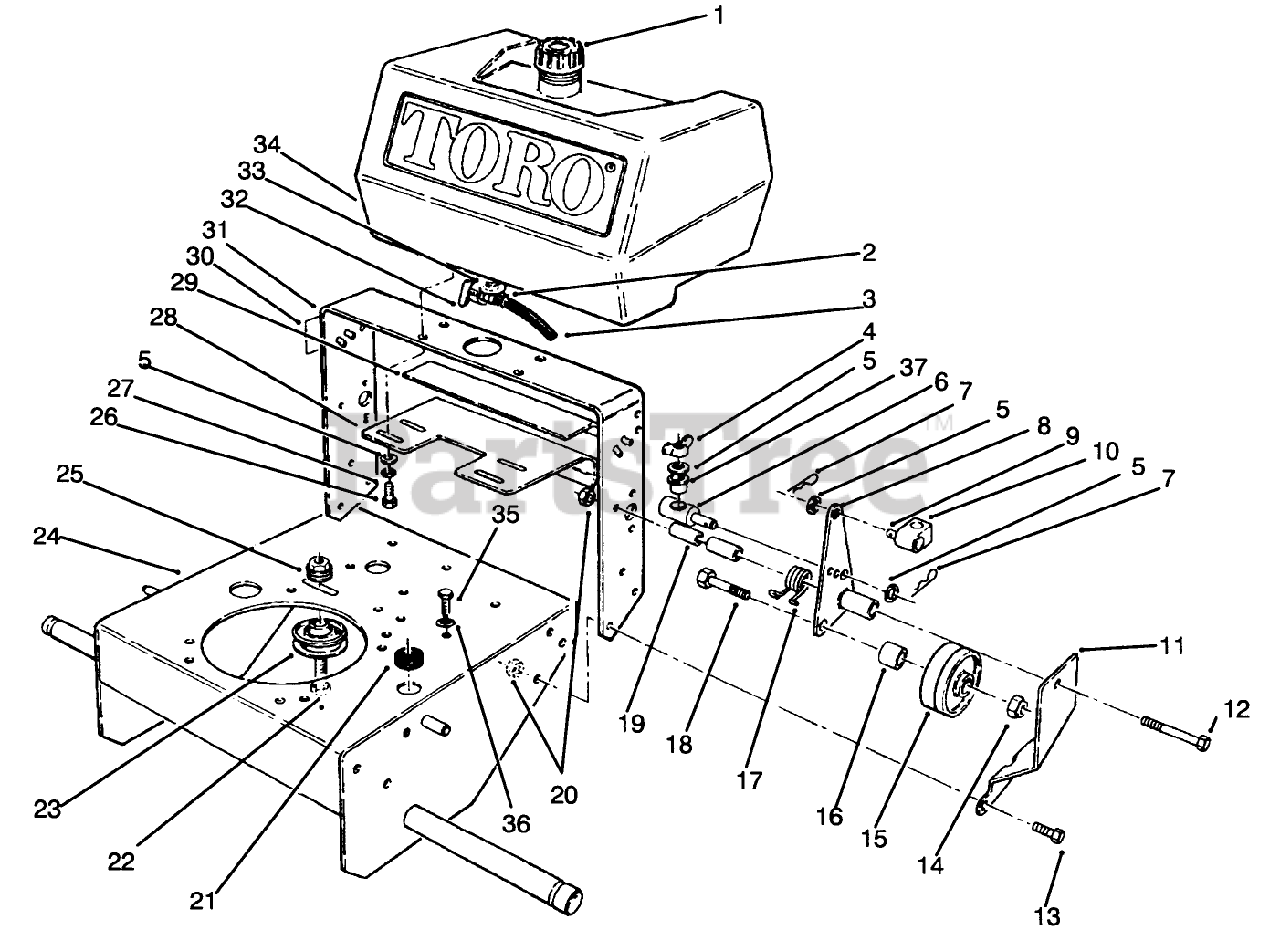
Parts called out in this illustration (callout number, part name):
1	GAS CAP ASM
4	NUT-WING
5	WASHER-PLAIN
6	FITTING-ROD
9	PIN-CLEVIS
10	FITTING-ROD
12	SCREW-HH
13	SCREW-HH
14	NUT-LOCK, NI
16	WHEEL IDLER SPACER
17	SPRING-TORSION, LH
18	SCREW-LEVELER
19	SPACER-PIVOT, IDLER
20	NUT-LOCK, NI
21	GROMMET
22	SCREW-HH
23	PULLEY-IDLER
24	FRAME *R
25	NUT-HF
26	SCREW-HH
27	WASHER-LOCK
30	DECAL - FUEL SHUT OFF
32	FUEL VALVE
33	O-RING
34	FUEL TANK
35	SCREW
36	WASHER-LOCK/EXT
37	BUSHING-NYLON
